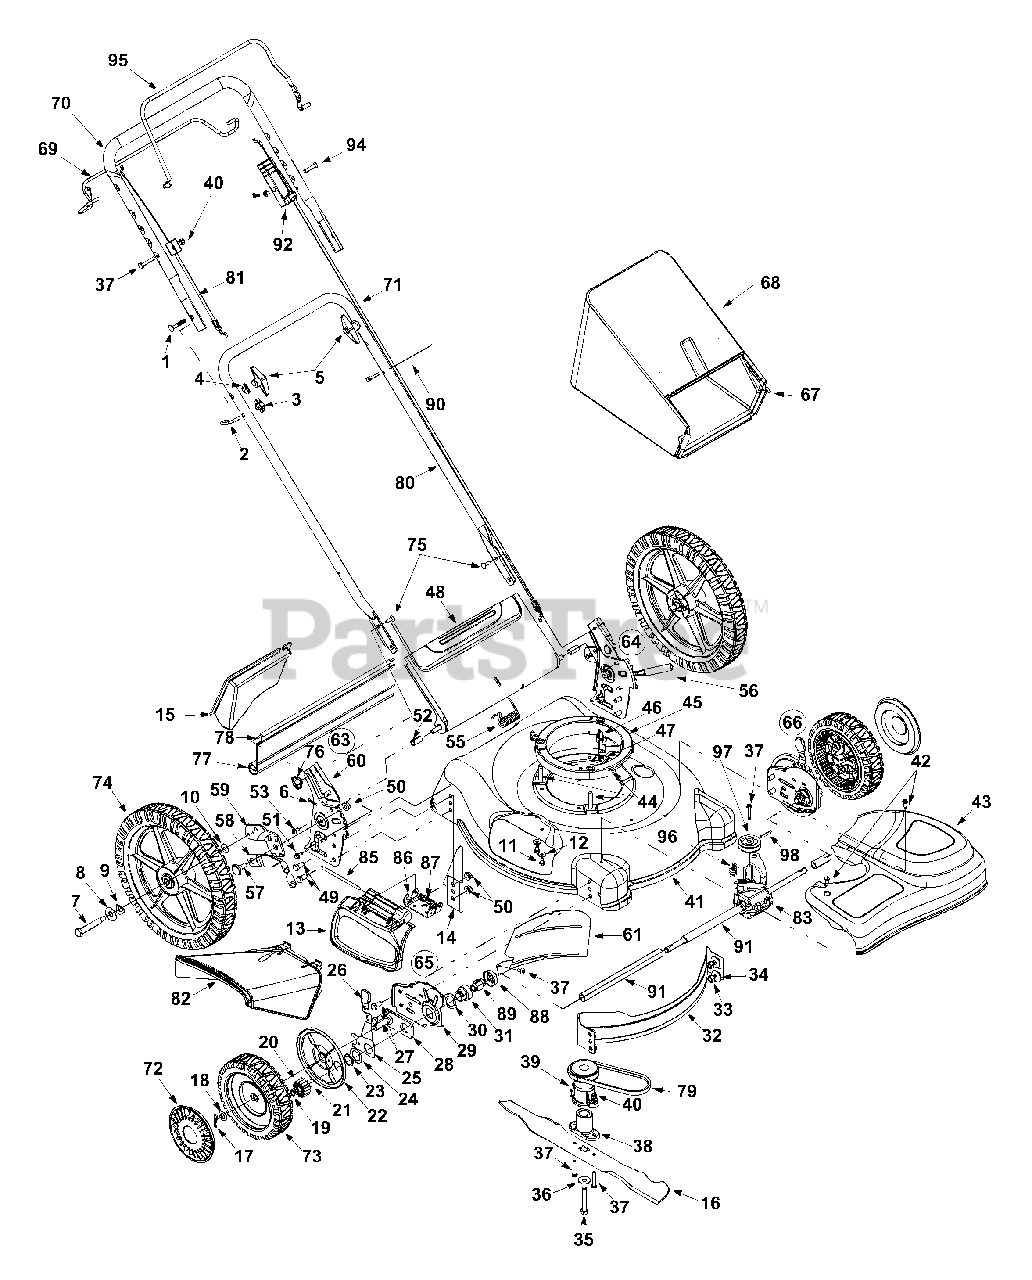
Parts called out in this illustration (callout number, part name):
1	Carriage Bolt
2	Rope Guide
3	Wing Nut
4	Saddle Washer
5	Handle Knob
6	Hairpin Clip
7	Shoulder Screw
8	Flat Washer .510 I.D. x 1.00 O.D.
9	Spring Wash. .500 I.D. x 1.00 O.D.
10	Bell Washer .375 I.D. x .870 O.D.
11	Tapp Screw 1/4-20 x .500
12	Bell Wash. .265 I.D. x .75 O.D.
13	Mulching Plug (Hinged)
15	Mulching Plug
16	Mulching Blade w/Star
17	Hairpin Clip
18	Flat Washer
19	Snap Ring
20	Gear 14T RH
21	Dowel Pin
22	Wheel Dust Cap
23	Snap Ring
24	Washer DD 1.5" O.D.
25	Front Lever Complete RH
26	Knob
27	Hex Screw
28	Pivot Plate Assembly
30	Wave Washer
31	Bearing Support
34	Bell Washer
35	Hex Bolt
36	Bell Washer
37	Hex Screw 1/4-20 x 1.5"
38	Blade Adapter
39	Drive Pulley
40	Hex Lock Nut
43	Transmission Cover, Yellow
44	TT Screw
45	Engine Spacer Assembly
46	Belt Keeper Pin
47	Hex Nut 1/4-20
50	Flange L-Nut 3/8-16
51	AB Tap Screw 1/4-14
52	Spacer
53	Pan Hd. Screw 1/4-20 x .5"
55	Torsion Spring
56	Foam Grip
57	Shoulder Screw
58	Spring Lever
60	Handle Bracket Assembly RH
65	Height Adjuster Ass'y Comp. RH
66	Height Adjuster Ass'y Comp. LH
68	Grassbag w/Yellow Logo
72	Hub Cap
73	Wheel 8 x 2 Zag Tread, Black
74	Wheel 14 x 2 Zap Tread, Yellow
75	Carriage Bolt
76	Wing Nut
77	Trail Shield
78	Wire
79	V-Belt
81	Drive Cable
82	Chute Deflector
83	Transmission Assembly Comp.
85	Hinge Pin
87	Torsion Spring
88	Bearing Retainer
89	Bearing Sleeve .50 I.D.
90	Cable Tie
92	Control Housing
94	C-Sunk Screw 1/4-20
96	Belt Tension Spring
97	Input Pulley
98	Roll Pin
